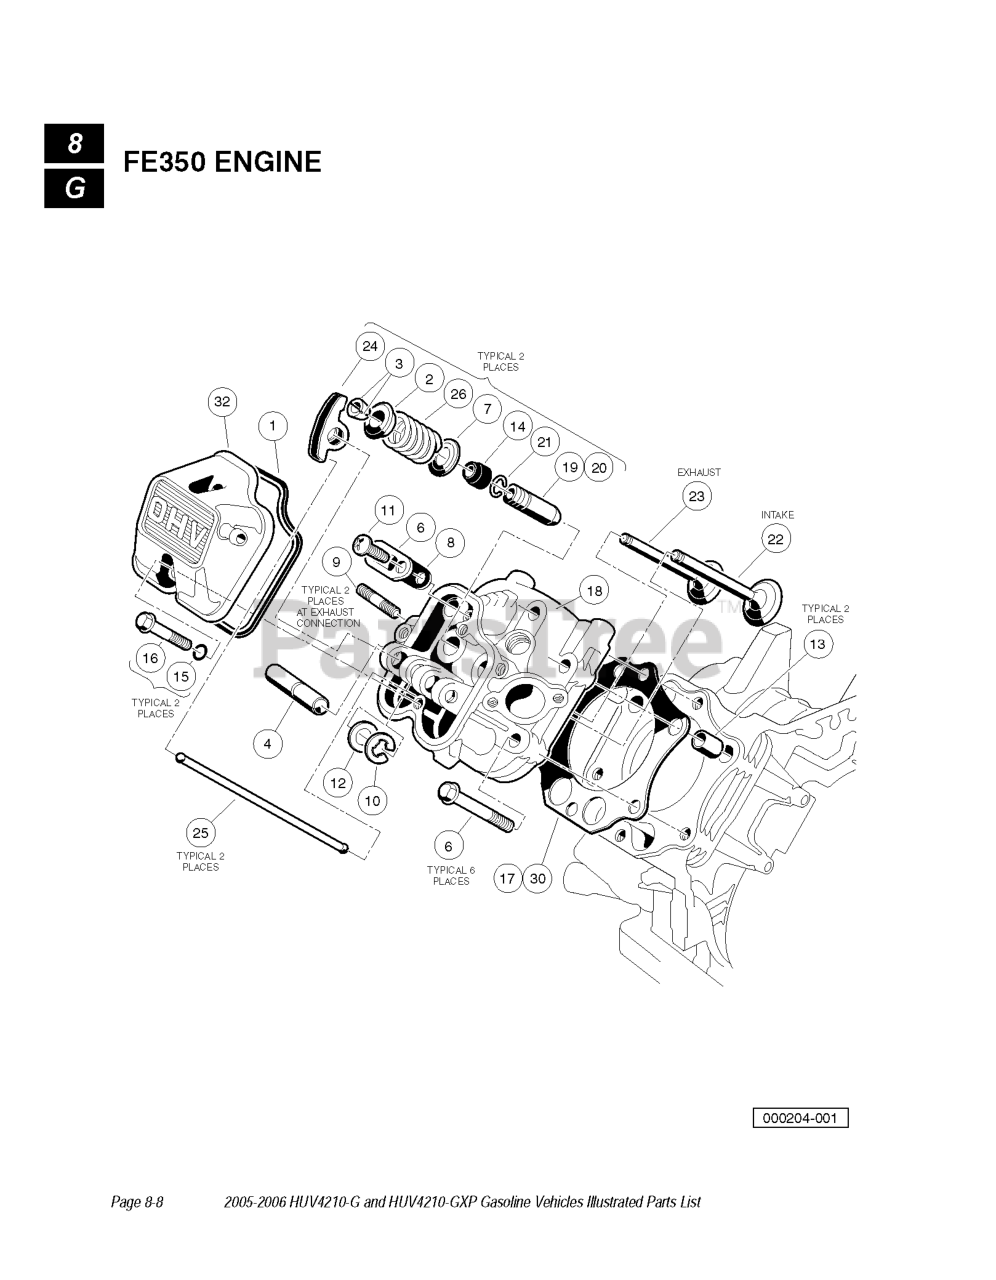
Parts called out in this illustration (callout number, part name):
1	GASKET, ROCKER CASE
2	RETAINER - VALVE SPRING
4	SHAFT - ROCKER
5	BOLT, FLANGED
7	SEAT, SPRING
9	STUD, M8-1.25 2-ENDED
10	CIRCLIP - TYPE - E
12	WASHER, 12.1X19X1.8
16	BOLT, 6X35
17	GASKET - HEAD
18	FE350 CYLINDER HEAD ASSEMBLY
19	GUIDE, VALVE, EXHAUST
20	GUIDE, VALVE, INTAKE
22	VALVE - INTAKE
23	VALVE - EXHAUST
24	ARM - ROCKER
25	ROD - PUSH
26	SPRING - ENGINE VALVE
27	GASKET KIT, FE350
28	GASKET, ENGINE TO INSULATOR
29	GASKET, FE350 EXHAUST
30	GASKET - HEAD
31	GASKET - CRANKCASE COVER
32	CASE, ROCKER -W/O LOGO FE290
